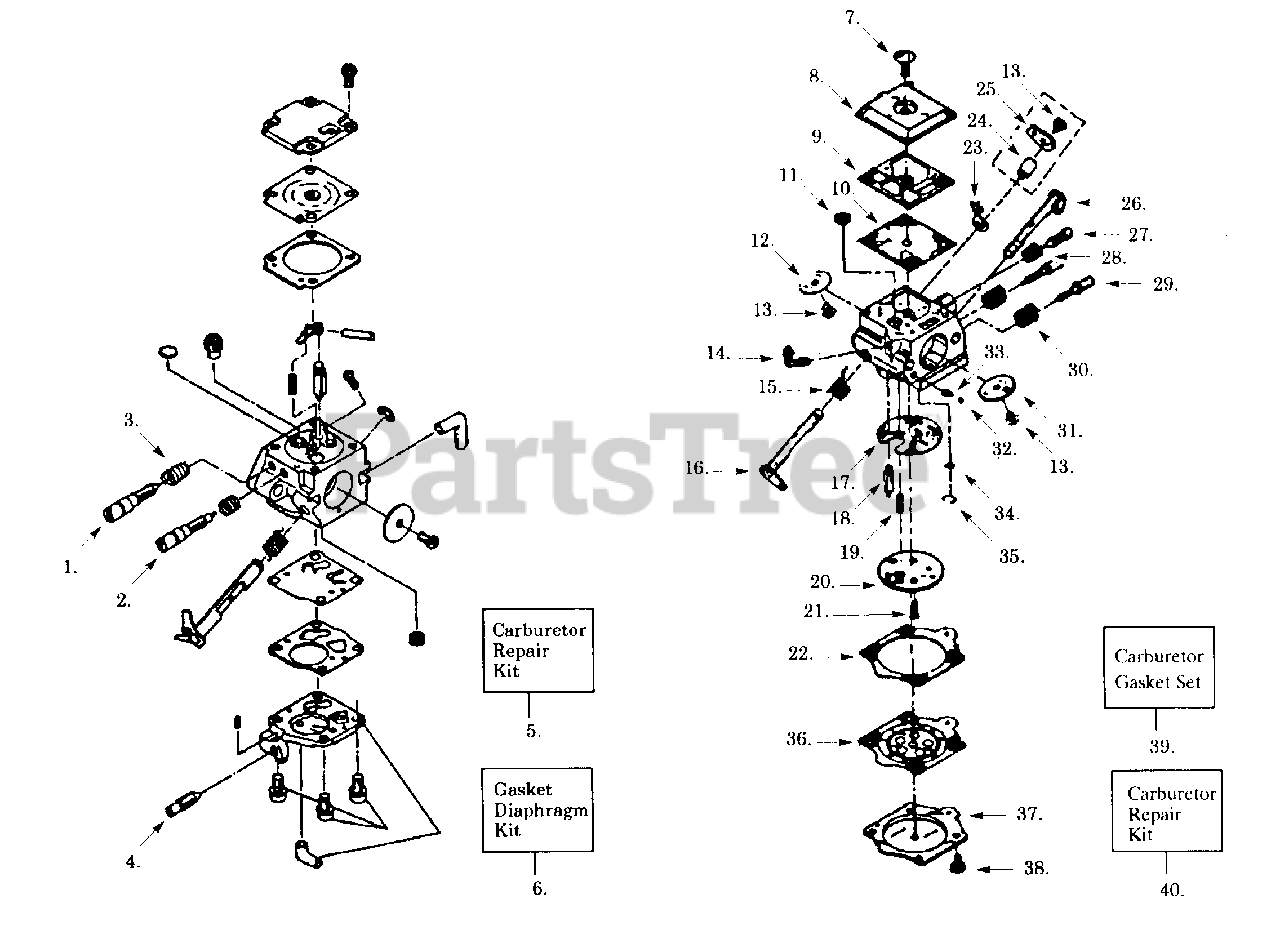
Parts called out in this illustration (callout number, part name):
1	Idle Low Mixture Screw
2	High Mixture Screw
3	Mixture Screw Spring
4	Idle Adjustment Screw
5	Carburetor Repair Kit
6	Gasket/Diaphragm Kit
7	Pump Cover Screw
8	Fuel Pump Cover
9	Fuel Pump Gasket
10	Fuel Diaphragm
11	Inlet Screen
12	Throttle Valve
13	Valve Screw
14	Fitting-Inlet Elbow
15	Throttle Ret. Spring
16	Throttle Shaft Ass'y.
17	Circuit Gasket
18	Inlet Needle Valve
19	Metering Lever Spring
20	Circuit Plate Ass'y.
21	Circuit Plate Screw
22	Mtg. Diaphragm Gasket
23	Throttle Stop
24	Throttle Lever Bushing
25	Throttle Lever-Outer
26	Choke Shaft Ass'y.
27	Idle Screw Spring
28	Idle Adj. Screw
29	Hi & Lo Needle
30	Needle Retainer Kit
31	Choke Valve
32	Choke Friction Ball
33	Choke Friction Spring
34	Check Valve Screen
35	Screen Retaining Ring
36	Diaph. Mtrg. Ass'y.
37	Mtrg. Diaphragm Cover
38	Mtrg. Cover Screw Ass'y.
39	Carb. Gasket Kit
40	Carb. Kwik Repair Kit
